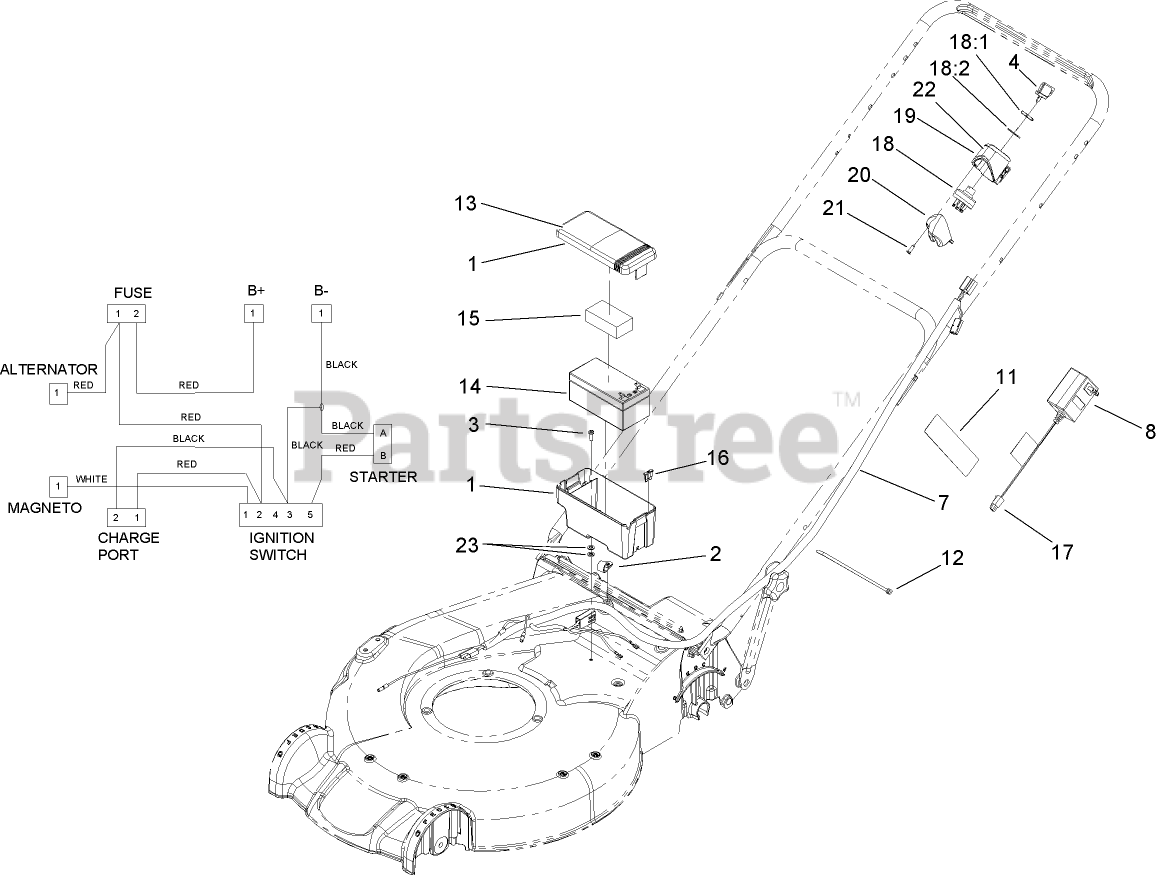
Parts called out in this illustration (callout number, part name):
1	BATTERY BOX ASM
2	CLAMP-R
7	HARNESS-WIRE
8	CHARGER-EUROPEAN, 12V DC
11	DECAL-WARNING
12	TIE-CABLE
13	DECAL-INSTRUCTIONAL
14	BATTERY-WET
15	FOAM-BATTERY, TOP
16	FUSE-40 AMP
17	ADAPTER-CHARGER
18	SWITCH-STARTER
18:1	NUT-HH
18:2	WASHER-LOCK
19	HOUSING-SWITCH, KEY
20	COVER-SWTCH
21	SCREW-PPH
22	DECAL-SWITCH, IGNITION
23	WASHER-FLAT
